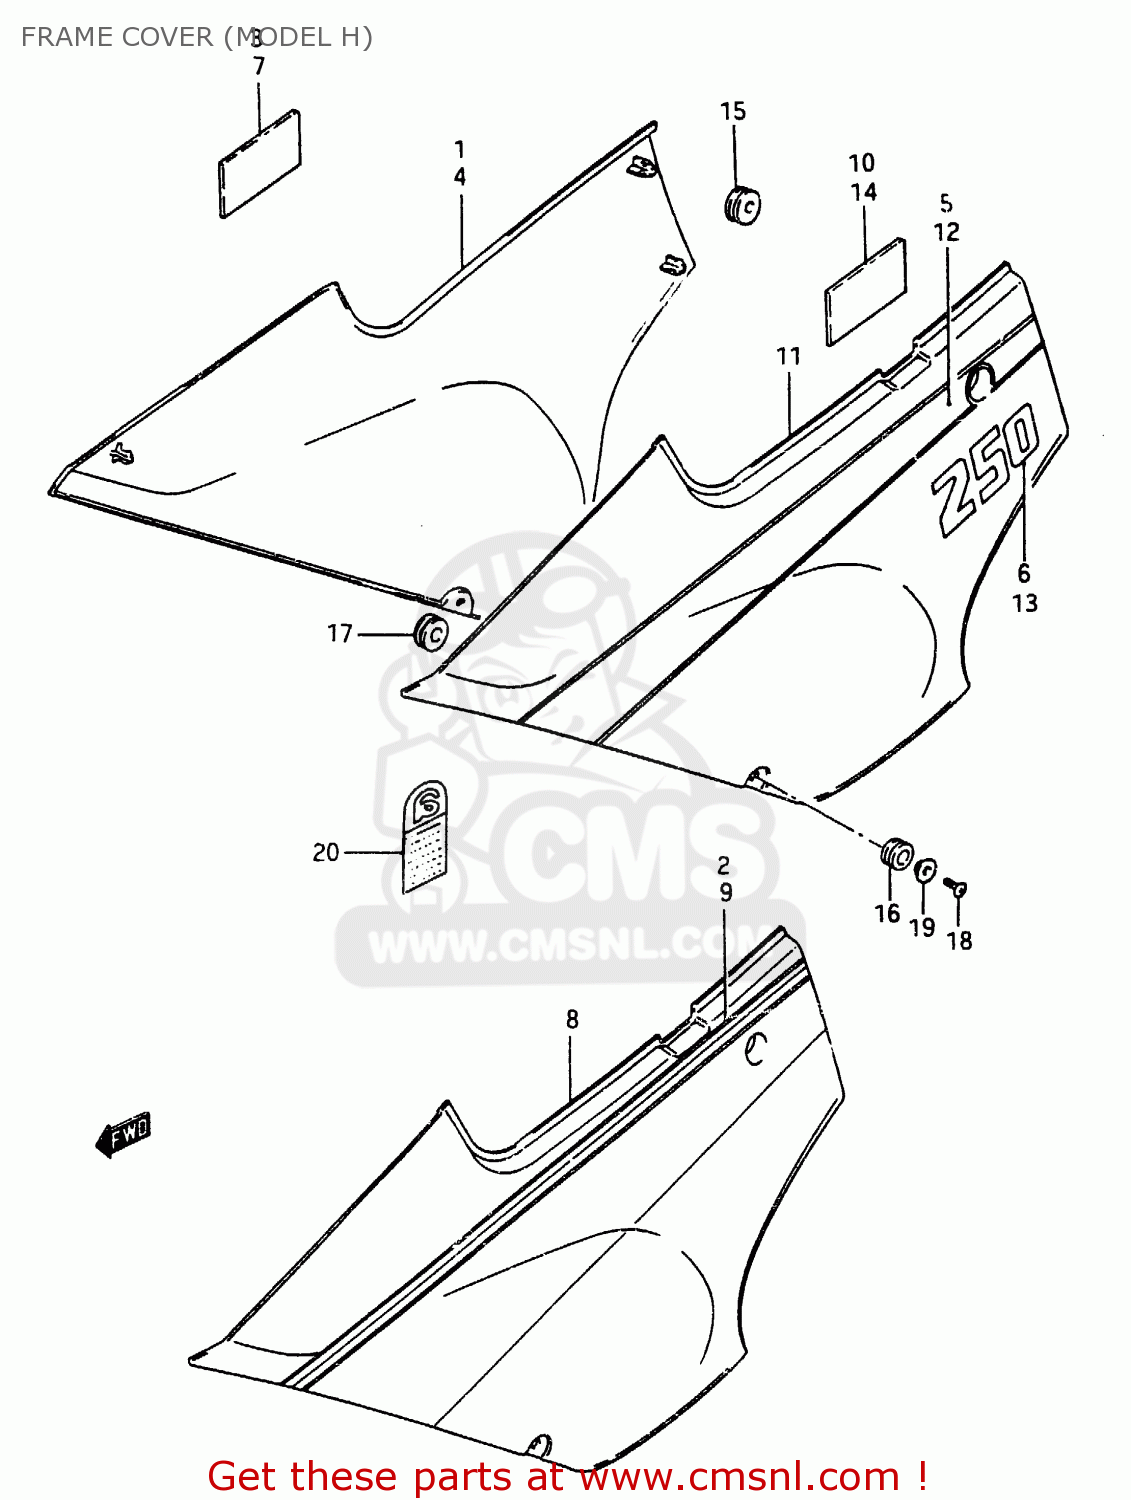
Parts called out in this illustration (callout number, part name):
1	COVER, FRAME RH
2	TAPE SET, FRAME COVER RH
3	PROTECTOR(170X95X3.0)
4	COVER, FRAME RH
5	TAPE SET, FRAME COVER RH
6	EMBLEM (WHITE)
7	PROTECTOR(170X95X3.0)
8	COVER, FRAME LH
9	TAPE SET, FRAME COVER LH
10	PROTECTOR,BATTERY
11	COVER, FRAME LH
12	TAPE SET, FRAME COVER LH
13	EMBLEM (WHITE)
14	PROTECTOR(170X95X3.0)
15	CUSHION
16	CUSHION
17	CUSHION,COVER HEAD
18	SCREW
19	WASHER
20	LABEL,ASBESTOS WARNING
